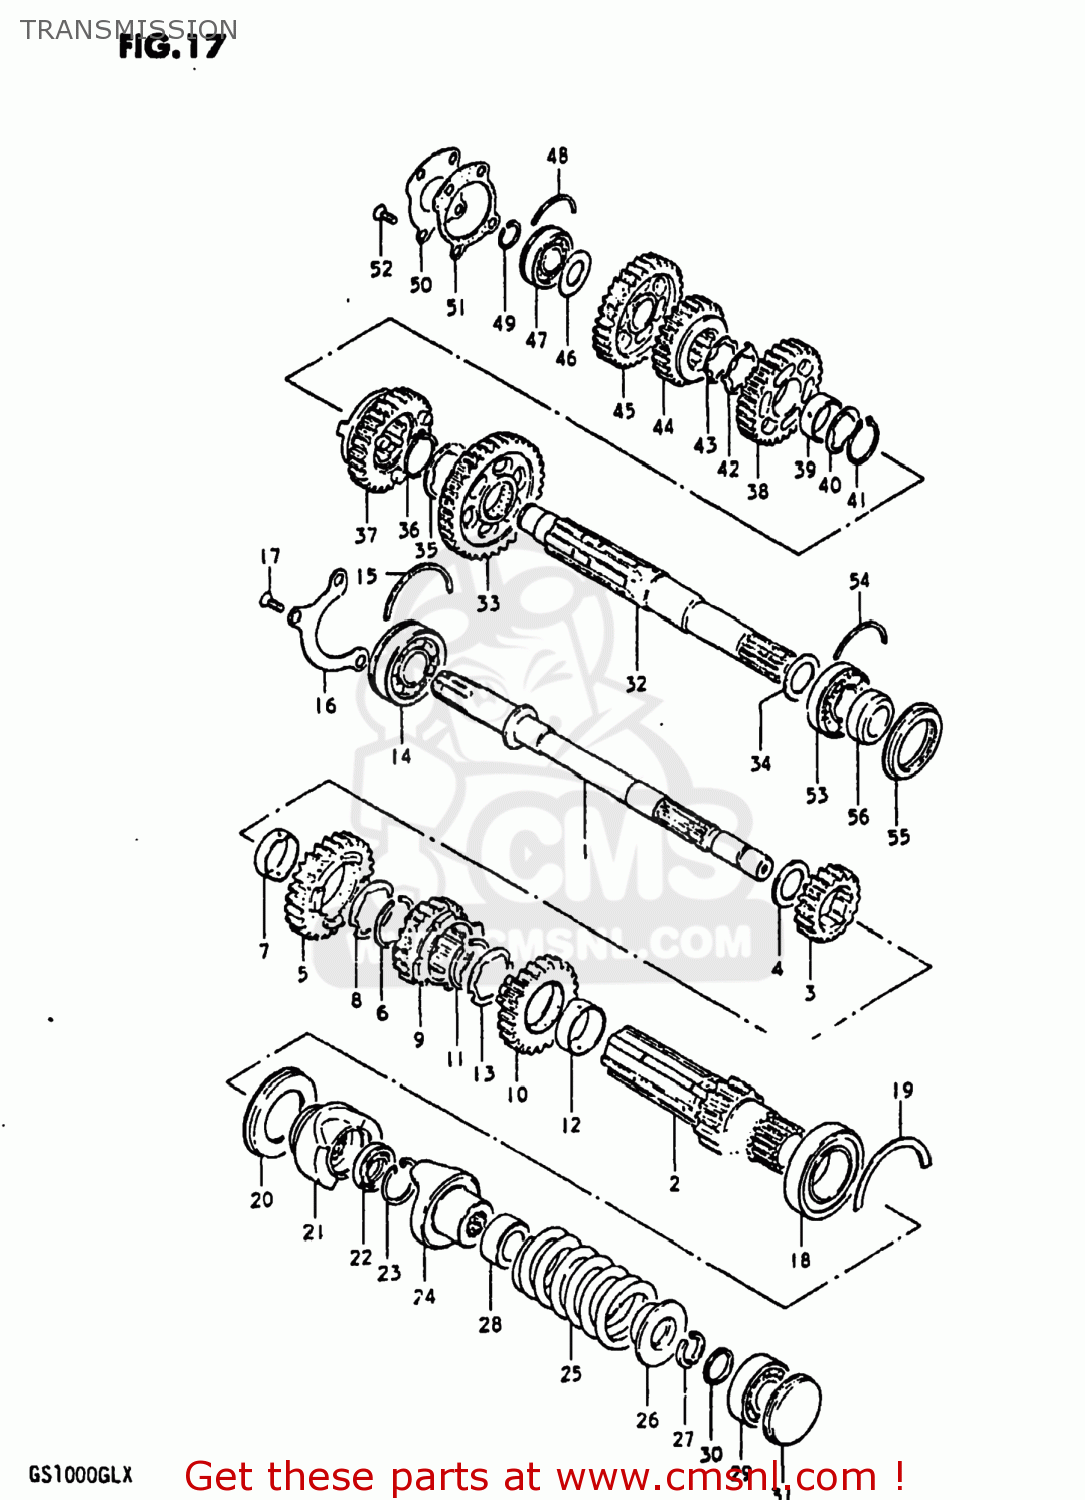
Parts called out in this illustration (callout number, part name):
1	SHAFT,COUNTER
2	SHAFT,OUTER COUNTER
3	GEAR,SECOND DRIVE
4	WASHER (21X35X2)
5	GEAR,5TH DRIVE(NT:26)
6	RING,SNAP
7	SPACER,DRIVE GEAR
8	LOCK WASHER,5TH DR GEAR SPACER
9	GEAR,THIRD DRIVE
10	GEAR,FOURTH DRIVE
11	RING,SNAP
12	SPACER,DRIVE GEAR
13	LOCK WASHER,5TH DR GEAR SPACER
14	BEARING(25X62X17)
15	C-RING
16	RETAINER,CNTR SHAFT BEARING
17	SCREW
18	BALL BEARING 32X58X13
19	C-RING
20	SEAL,OIL(40X58X7)
21	DOG,OUTPUT CAM
22	SEAL,OIL(20.6X31X6)
23	CIRCLIP
24	DOG,INPUT CAM
25	SPRING
26	STOPPER,CAM DOG
27	STOPPER,CAM DOG
28	GUIDE,CAM DOG SPRING
29	BEARING
30	SPACER (17X21X3.5)
31	PLUG
32	SHAFT,DRIVE
33	GEAR,FIRST DRIVEN
34	WASHER, LH
35	WASHER,LOCK
36	CIRCLIP
37	GEAR,FOURTH DRIVEN
38	GEAR,THIRD DRIVEN
39	BUSH,3RD DRIVEN GEAR
40	WASHER,LOCK
41	CIRCLIP
42	WASHER
43	WASHER,LOCK
44	GEAR,FIFTH DRIVEN
45	GEAR,SECOND DRIVEN
46	WASHER
47	BEARING(20X47X14)
48	C RING
49	CIRCLIP
50	PLATE,DRIVESHAFT
51	GASKET,DRIVESHAFT PLATE (MCA)
52	SCREW
53	BEARING
54	C RING
55	SEAL,OIL(35X52X6)
56	SPACER,DRIVESHAFT,LEFT
